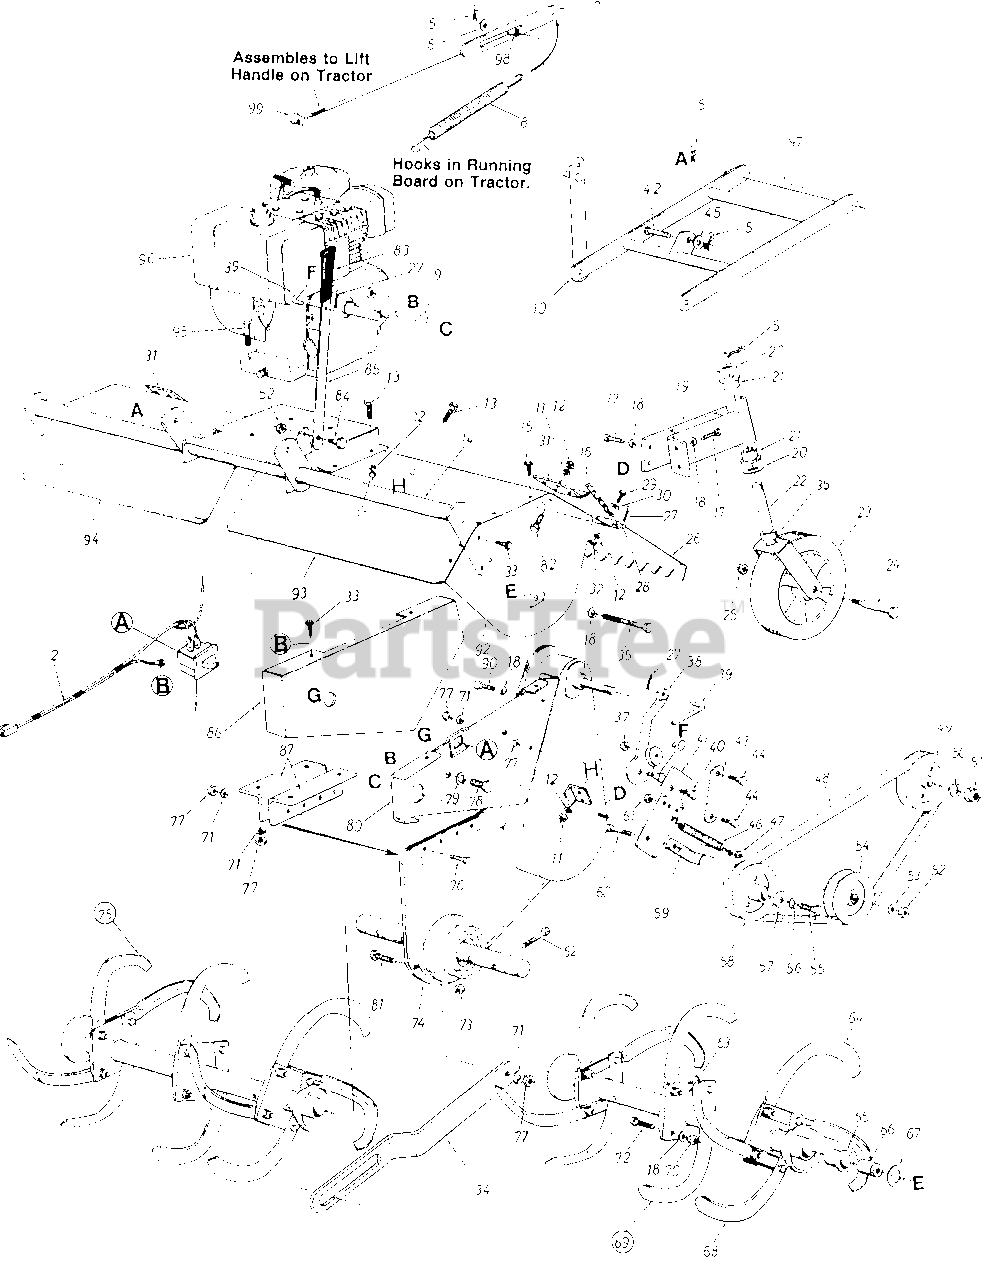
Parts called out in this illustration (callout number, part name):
1	Safety Switch
2	Wire Harness
5	Internal Cotter Pin
6	Fl-Wash. 1/2" I.D. x .93" O.D.
9	Sq. Key 1/4" x 1/4" x 2.00" Lg.
12	L-Wash. 1/4" I.D.
13	Hex Bolt 1/4-28 x .62" Lg.
16	#2 Dog Chain x 20" Lg.
17	Hex Wash. Hd. Self-Tap Scr. 3/8-24 x .75" Lg.
18	L-Wash. 3/8" I.D.*
21	Flange Bearing 3/4" I.D. x 1.00" O.D.
24	Shoulder Bolt .623" I.D. x 3.62" Lg.
25	Hex Cent. L-Nut 7/16-14 Thd.
28	L.H. Flap Rod
29	Hex Bolt 1/4-20 x .62" Lg.
30	Fl-Wash. 1/4" I.D.
33	Hex Wash. Hd. Self-Tap Scr. 1/4" x.62" Lg.
36	Spacer .752" I.D. x 1.25" O.D.
37	Hex Cent. L-Nut 5/16-18 Thd.
40	Shoulder Bolt 7/16" Dia. x 1.75" Lg.
41	Idler Bracket
45	Fl-Wash. .50" I.D. x 1.0" O.D. x .06
46	Extension Spring .62" O.D. x 6.12" Lg.
47	Hex Crown Nut 3/8-24 Thd.
48	"V"-Belt (Kevlar)
49	1/2" "V"-Pulley 4.75" O.D. x .625" Bore
50	L-Wash. 5/8" I.D.*
51	Hex Ins. L-Nut 5/8-18 Thd.
52	Hex Cent. L-Nut 3/8-16 Thd.
53	Fl-Wash. 3/8" I.D.
54	Idler Pulley 4.0" O.D.
56	L-Wash. 7/16" I.D.*
57	Fl-Wash. 7/16" I.D. x 1.38"
58	1/2" "V"-Pulley .475" O.D. x 1.00" Bore
61	Hex Cent. L-Nut 5/16-18 Thd.
62	Hex Bolt 7/16-14 x 2.00" Lg.
67	Thrust Wash. 1/2" I.D. x 1.55"
71	L-Wash. 5/16" I.D.*
72	Hex Bolt 3/8-24 x 1.5" Lg.*
73	Hex Cent. L-Nut 7/16-14 Thd.
77	Hex Nut 5/16-18 Thd.*
78	Hex Bolt 1/2-20 x .88" Lg. (Grade 5)
79	L-Wash. 1/2" I.D.*
80	Clutch Support Bracket
81	Shld. Bolt .435 Dia. x .265 0 5/16-18 Thd.
82	Hex Bolt 1/4-28 x .75" Lg.
83	Plastic Grip
84	Shoulder Bolt .498 Dia. x .212 Lg.
85	Clutch Handle
96	8 H.P. Engine
98	Push Bar Sleeve .503" I.D. x.624" O.D.
